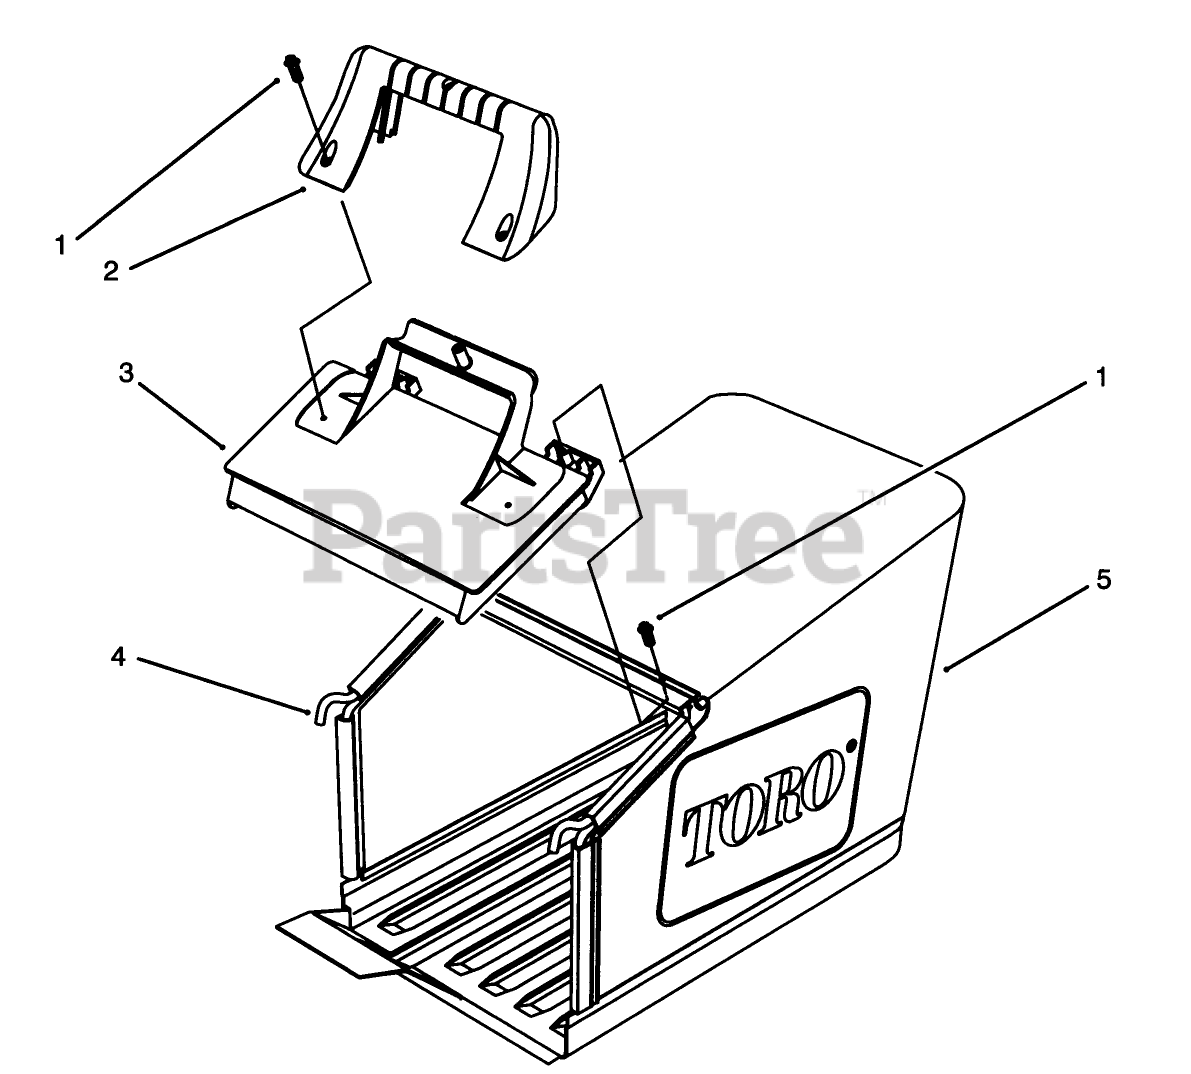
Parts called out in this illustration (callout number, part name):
1	SCREW-PPH
2	HANDLE-DOOR
3	DOOR-BAG
4	Frame
5	BAG-GRASS
